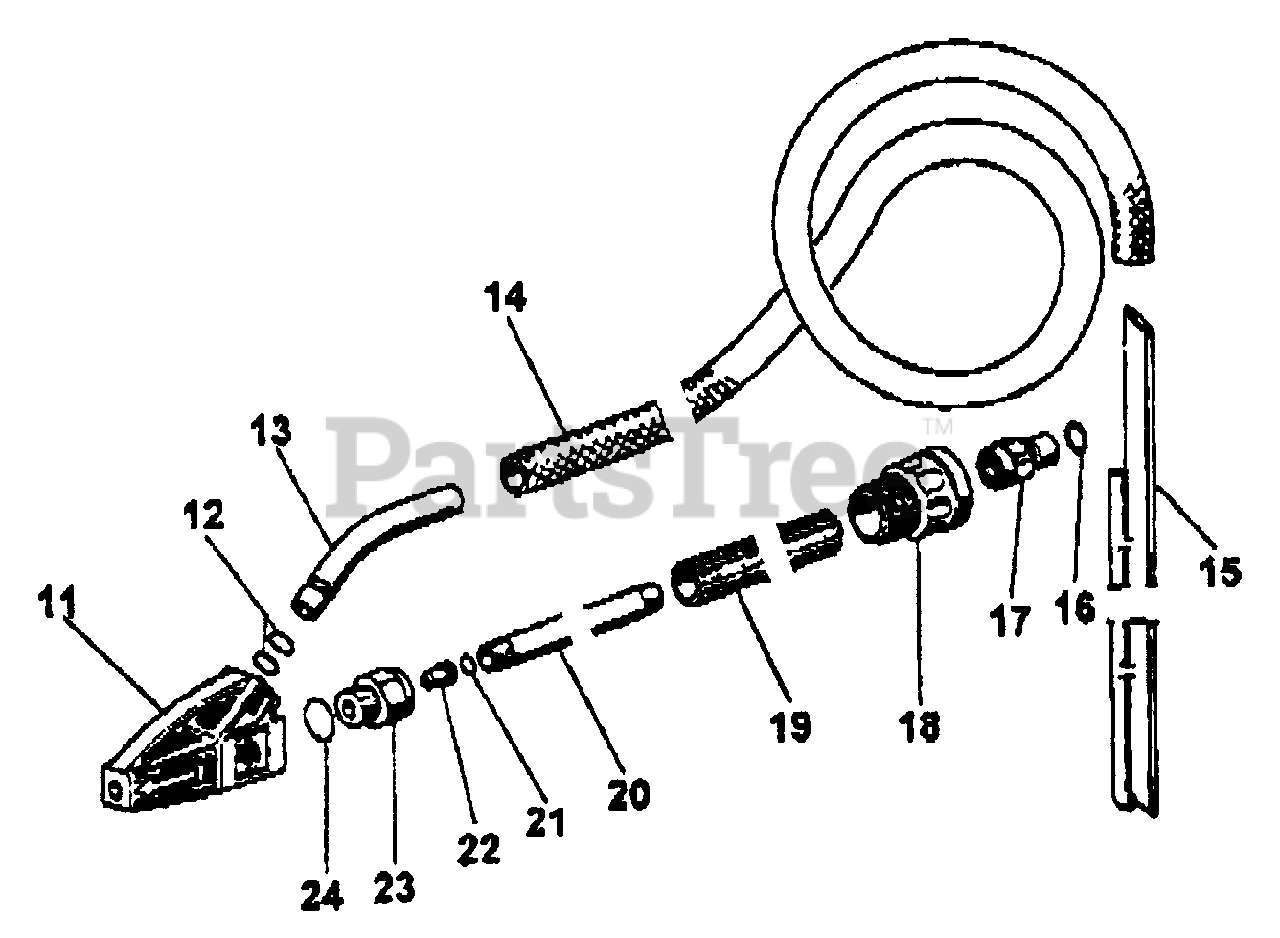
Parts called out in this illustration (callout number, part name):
11	NOZZLE, SAND
12	O-RING
13	CONNECTOR, SAND TUBE
14	TUBE, SAND
16	O-RING
17	COUPLING, MALE
18	NUT, RING
19	GRIP, HANDLE
20	PIPE
22	NOZZLE, SAND BLASTING
23	HOLDER, NOZZLE
24	O-RING, 0.614×0.070
